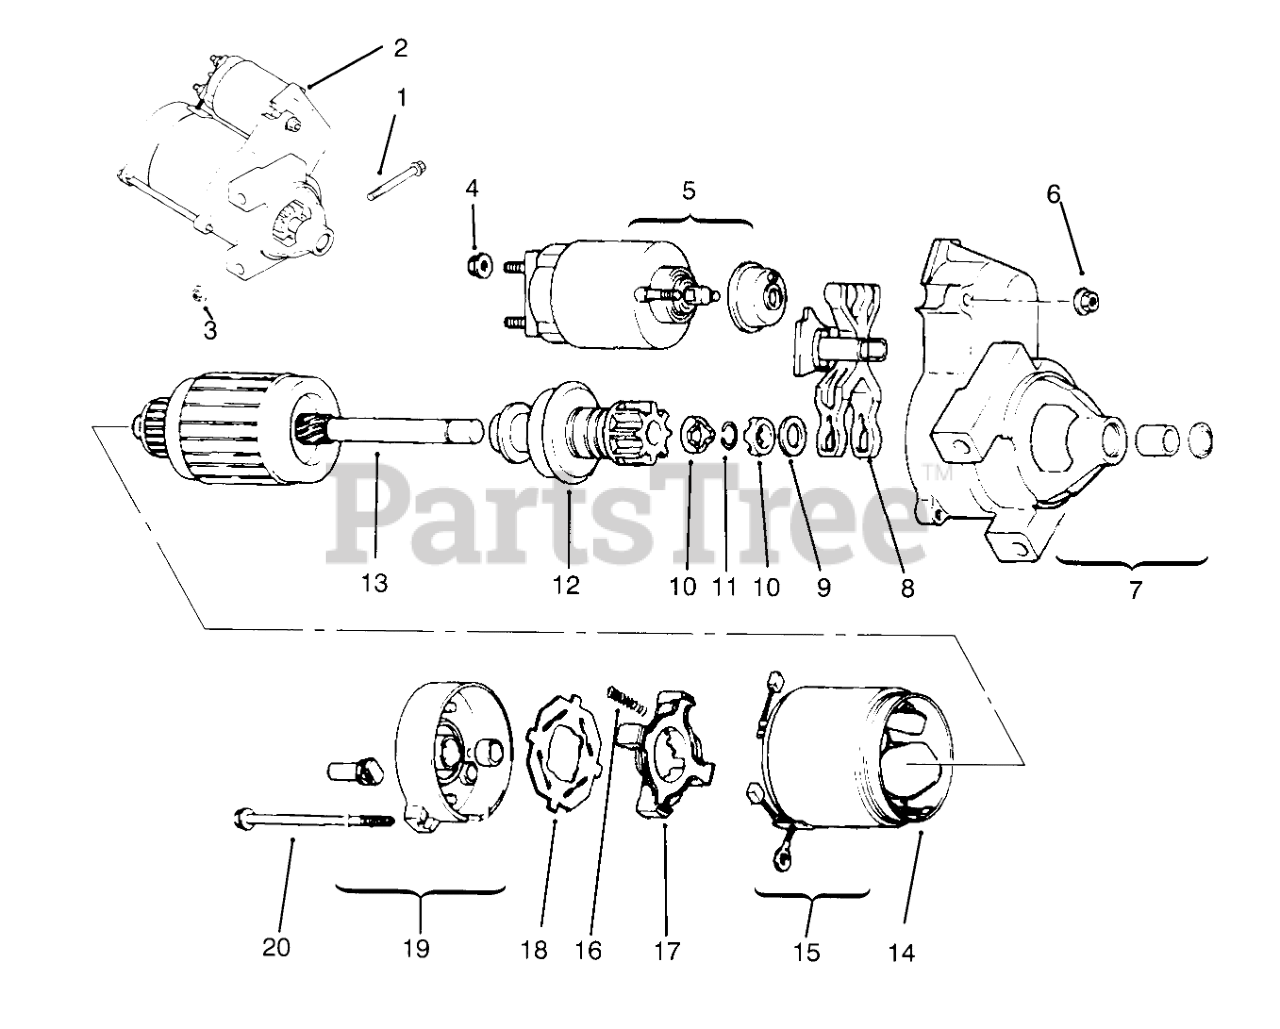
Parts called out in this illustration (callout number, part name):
2	Starter INC 4-20
3	Nut
4	Nut
5	Solenoid
6	Nut
7	Cap Drive End
8	Lever Starter Drive
9	Washer-Thrust
10	Nut
11	Ring-Retainer
12	Drive Pinion
13	Armature
14	Frame
15	Brush Kit
16	Spring Brush
17	Holder-Brush
18	Insulator
19	Cap-Commutator End
20	Bolt
